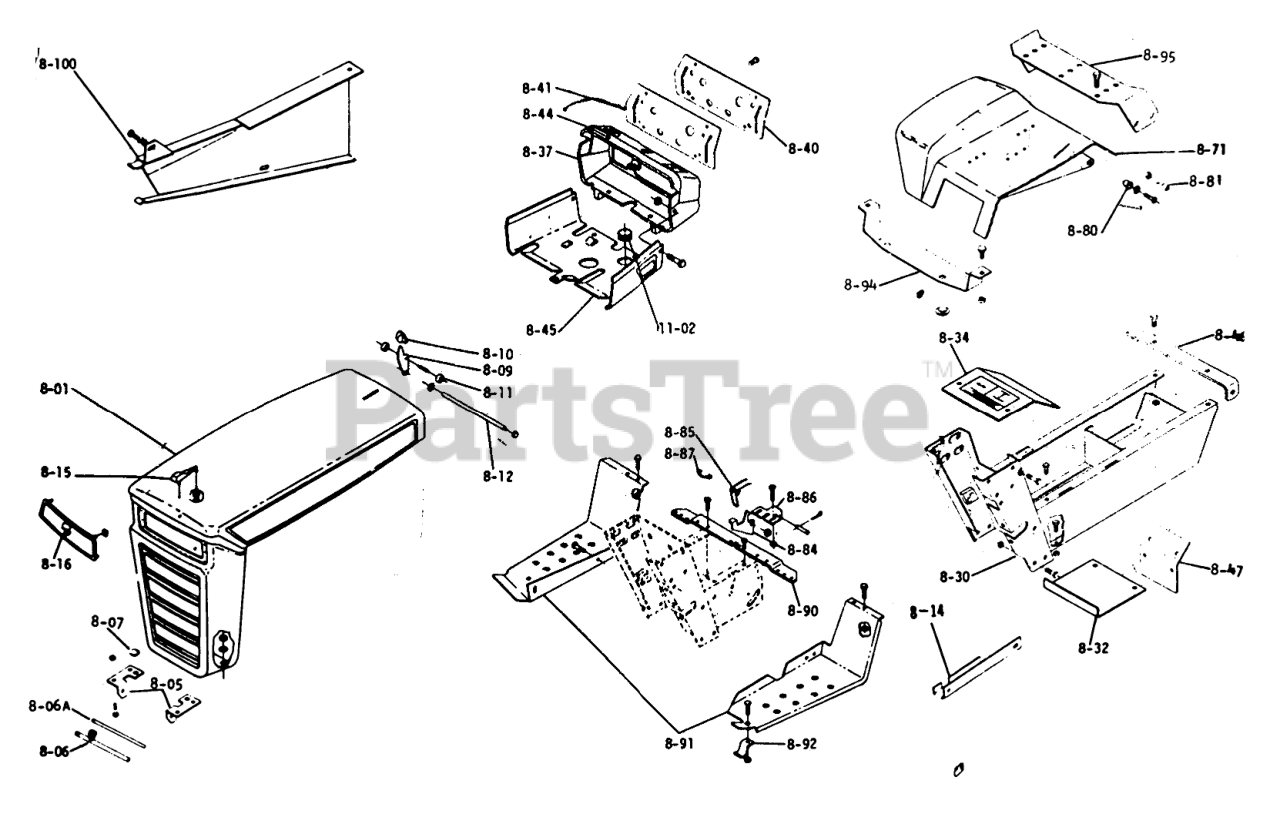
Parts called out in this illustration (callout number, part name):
8-01	Hood
8-05	Bracket-Grille Pivot-R.H.
8-06	GRILL PIVOT ROD
8-06A	ROD-HOOD STOP
8-09	LEVER HOOD LATCH
8-10	KNOB
8-11	Roller
8-12	Rod Latch
8-14	Channel
8-15	Hood Ornament
8-16	ESCUTCHEON PLATE
8-30	Hoodstand Assy.
8-32	Cover-Dust
8-34	Plate-Cover
8-37	Housing
8-40	Panel
8-41	BACK UP PLATE
8-44	Tape
8-45	Support-Fuel Tank
8-46	Bracket
8-47	Bracket Instrument
8-71	Fender
8-80	BUSHING-FLANGED
8-81	SPACER
8-84	Latch Fender
8-85	Spring
8-86	BRACKET FENDER LATCH
8-87	Stop-Fender Latch
8-90	Bracket
8-91	Footrest R.H.
8-92	Footrest-R.H.
8-92	BRACKET
8-94	Fender Bracket
8-95	Bracket Fender Hinge
8-100	Belt Guard Assy.
